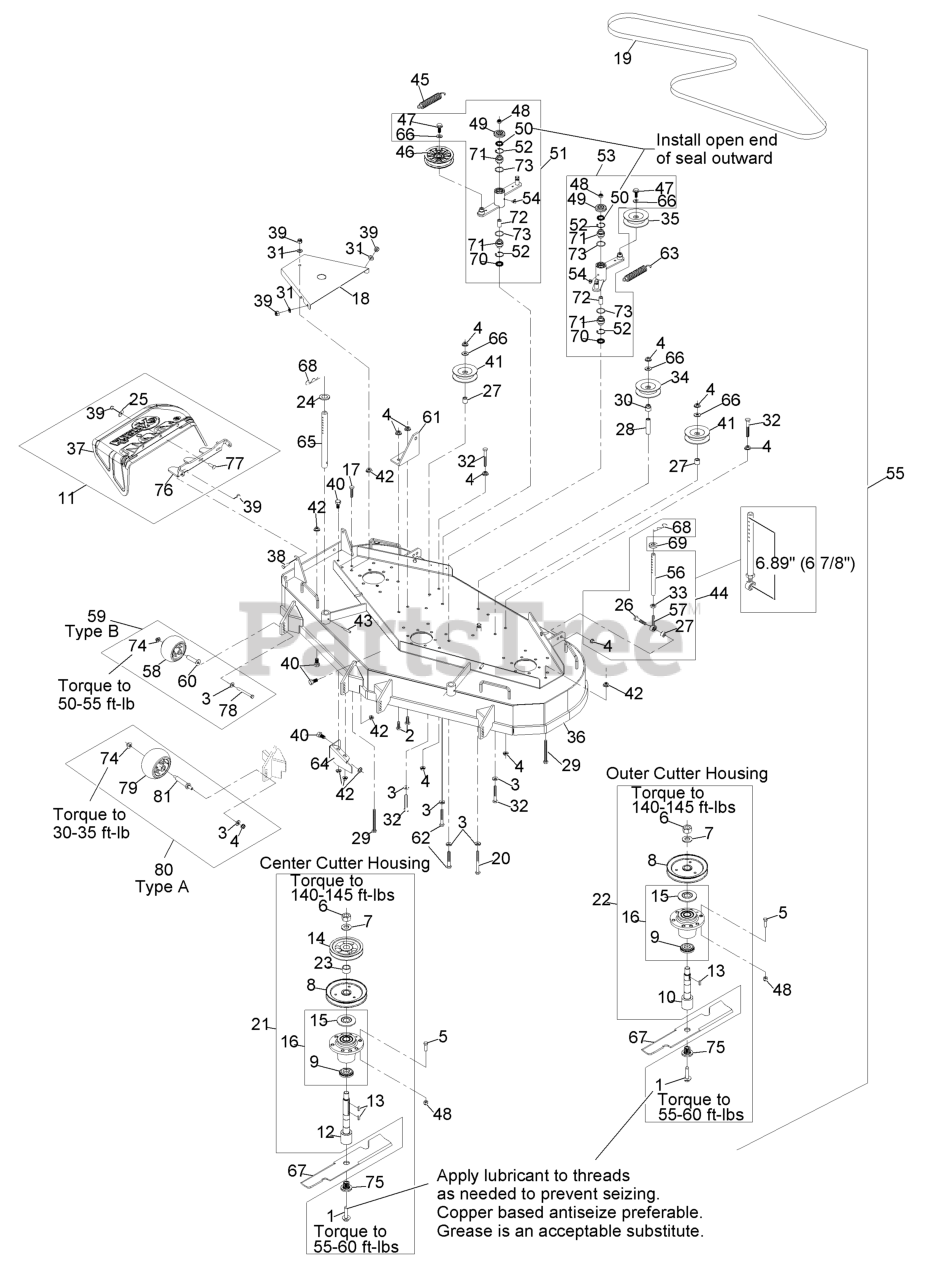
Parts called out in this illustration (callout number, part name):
1	SCREW,SEMS 1/2-20 X 2.19
2	SCREW-HH
3	WASHER-BELLEVILLE
4	NUT-HHF, WHIZ
5	SCREW-HH
8	SHEAVE,BLADE DRIVE 6.30
9	SPACER-GUARD, BOTTOM
10	KIT, SPLINED SPINDLE 103-
11	ASM,FMD DISCHARGE CHUTE
12	KIT, SPLINED SPINDLE 103-
14	SHEAVE,MOWER DRIVE
15	GUARD-BEARING, TOP
16	KIT, CUTTER HOUSING
17	SCREW-HH
18	SHIELD,BELT SIDE FMD524
19	BELT,BLADE DRIVE FMD524
20	SCREW-HH
21	ASM,CUTTER HSG FMD524 CTR
22	ASM, CUTTER HSG COMPLETE
23	SPACER,TUBE
24	SPACER-DECK SUPPORT
25	WASHER-FLAT
26	SCREW-HH
28	SPACER-ANCHOR, CLUTCH
29	BOLT,TAP HH
30	BUSHING,IDLER
31	WASHER-FLAT
32	BOLT-CARR
33	NUT-HJ
34	PULLEY-IDLER
35	PULLEY-IDLER
36	ASM, DECK W/ DECALS FMD52
37	CHUTE,DISCHARGE
38	SCREW-HH
39	NUT-LOCK, NI
40	SCREW-HH
41	IDLER,PULLEY
44	KIT,SUPPORT LINK W/PIN
45	SPRING-EXTENSION
46	PULLEY-IDLER, FLAT
47	SCREW-HHF
48	NUT-LOCK, NI
49	GUARD-TOP
50	SEAL-LIP, SINGLE
51	KIT, IDLER ARM W/BEARINGS
52	RING-SNAP
53	KIT, IDLER ARM W/BEARINGS
54	FITTING-GREASE, 90 DEG
55	Asm, Complete Deck
56	LINK,SUPPORT
57	BALLJOINT
58	ROLLER-SCALP, ANTI
59	KIT, ANTI-SCALP ROLLER
60	AXLE, ROLLER
61	BRACKET,SPRING ANCHOR
62	SCREW-HH
63	SPRING-EXTENSION
64	BAFFLE,DISCHARGE
65	ROD,DECK SUPPORT
66	WASHER-FLAT
68	PIN,HAIR COTTER
70	SEAL-LIP, DOUBLE
71	BEARING-SPHERICAL
72	BUSHING-LEVER, LIFT
74	Nut-Nyloc 3/8-16 Flg
75	BUSHING,SPLINED
76	BRACKET, DISCHARGE CHUTE
77	SCREW-CARR
78	SCREW-HH 3/8-16 X 3 3/4 GR 8
79	ROLLER-SCALP, ANTI
